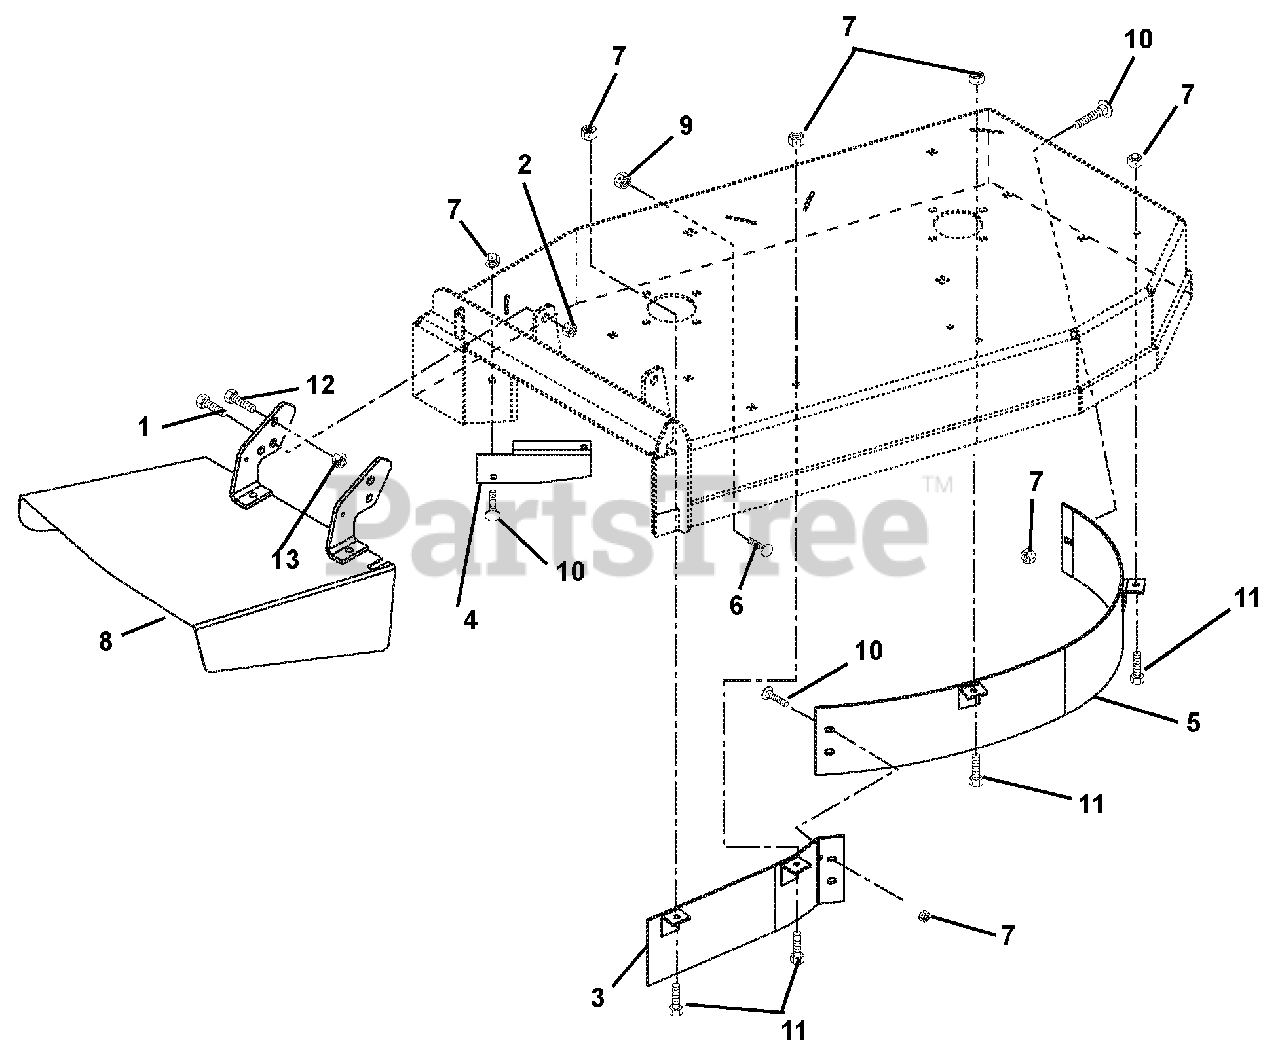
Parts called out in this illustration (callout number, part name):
1	Bolt-Hex .50-13 x 1.25 Grade 5
2	Nut-Locking-Nylon .50-13
3	Weldment- Upper Baffle Right
4	Deflector 32"
5	Weldment- Upper Baffle Left
6	Bolt-Round Head Square Neck .38-16 x 1.00 Grade 5
7	Nut-Locking-Top-Flange .31-18
8	Chute-Discharge
9	Nut-Locking-Top-Flange .38-16
10	Bolt-Round Head Square Neck .31-18 x .75 Grade 5
11	Bolt-Hex .31-18 x .75 Grade 5
12	Bolt-Hex .38-16 x .75 Grade 5 (312, 314)
13	Nut-Locking-Center .38-16 (312, 314)
